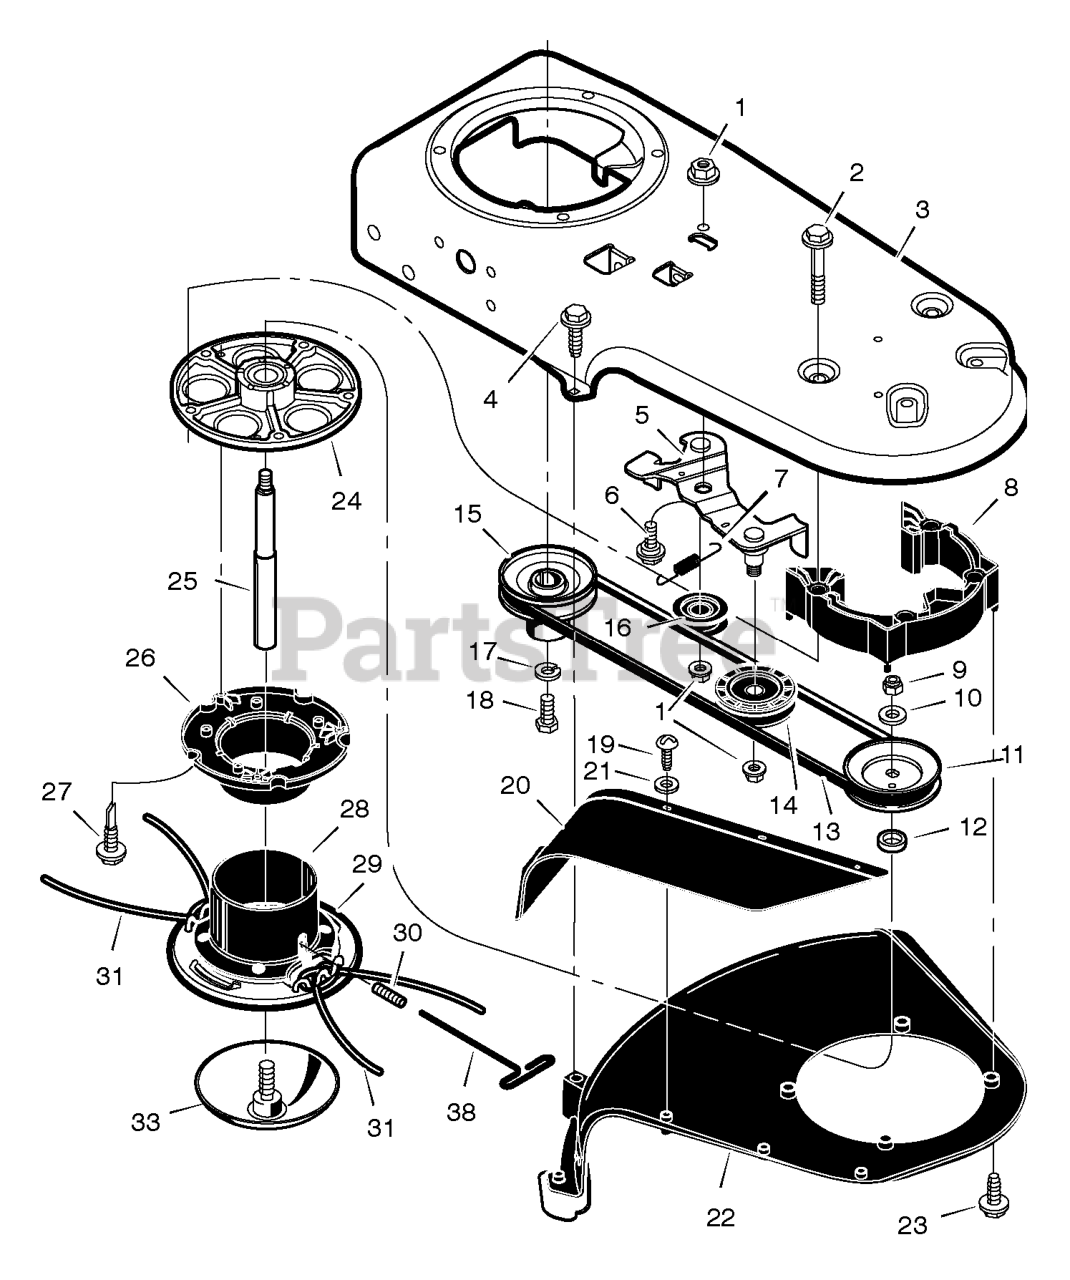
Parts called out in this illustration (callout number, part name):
1	Nut
5	Bracket, Idler Assembly
7	Spring, Extension
8	Spacer Assembly, Jackshaft
10	Washer, Flat
11	Pulley, Cutting Head
12	Spacer, Upper Pulley
13	Belt, Trimmer
14	PULLEY, IDLER, V, 1.88
15	Pulley, Engine
16	Pulley, Idler
17	Lockwasher
20	Flap, Debris
21	WASHER
22	Shield, Trimmer
24	Housing, Jackshaft
25	Shaft, Cutting Head
26	Wrap, Weed -Upper
28	Wrap, Weed -Lower
29	Assembly, Cutter Head & Wrap
30	Screw, Set
31	Line, Trimmer 0.155 X 21.25
33	Guide Assembly, Metal Height
38	Wrench, T-Handle
